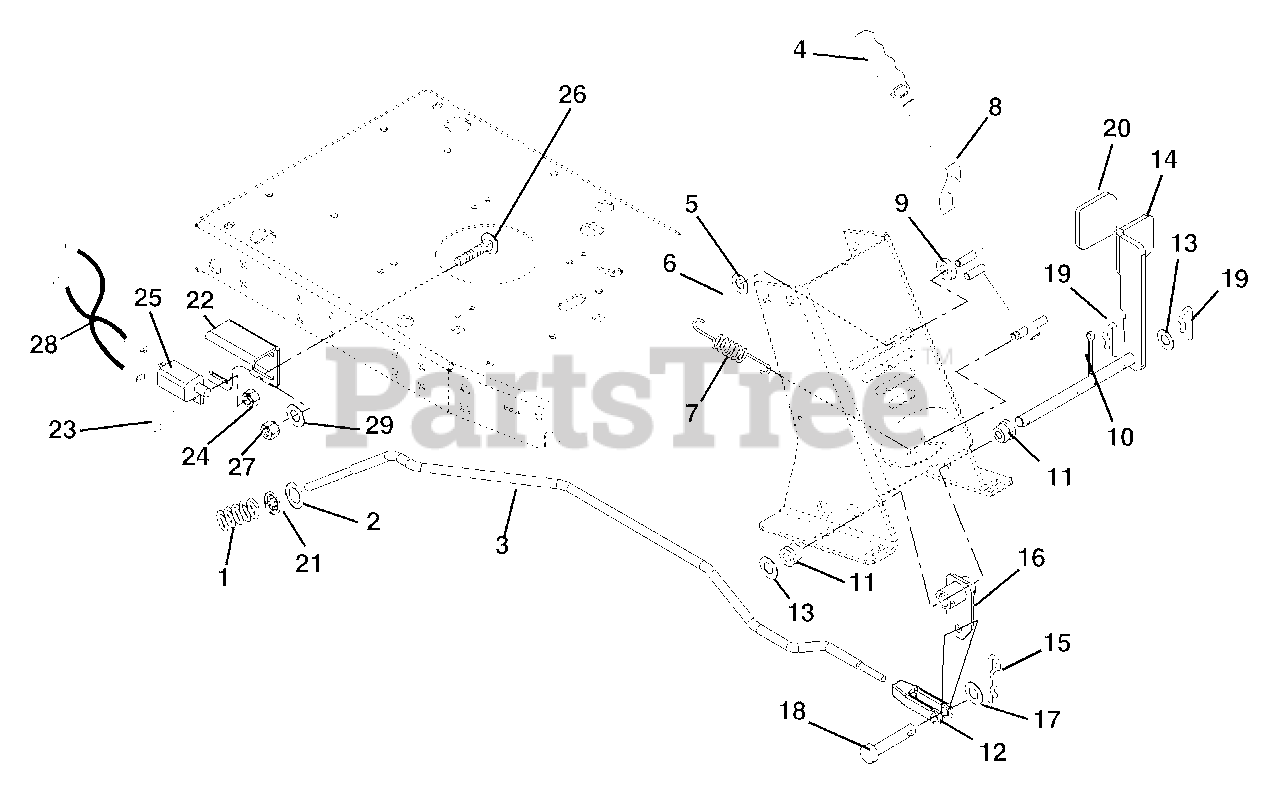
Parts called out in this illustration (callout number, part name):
1	SG-COMP .080X.52X2.90
2	WASHER, FLAT .33/2.125/.098
3	ROD, RER BRAKE
5	@WSHR-FL-STL.38X.875X.083 YWZC
6	NUT-LK-TOP-FLG .38-16 BLKZC
7	SG-TENS .048X.44X2.25 WLD 9
8	HANDLE, PARK BRAKE (WLDMNT)
9	BSHG-FLG .406X.88X.270X.140
10	@PIN-CTR .12X1.00 EXTPRSQCT YZ
11	BSHG-FLG .515X.750X.745X1.00NY
12	YOKE, .312-24 X 2.25
13	WSHR-FL-STL .505X1.00X.062YWZC
14	WLDMT-BRAKE PEDAL
15	PIN-HAIR, ENDRIES #25 YWZC
16	BRAKE ROD ARM & HUB
17	WSHR-FL-STL .328X.87X.179 YWZC
18	PIN-CLEV .312X.822 HDND PL
19	CLIP, SPRING
20	GRIP, PEDAL
21	NUT-PUSH .312
22	BRKT, SWITCH MOUNT
23	@SCR-MCH 10-24X.75 HWH YWZC
24	@NUT-LK-NYL 10-24 W/INSRT YWZC
25	SWITCH- SINGLE POLE N.O.
26	BLT-RDHDSQNK .38-16X1.00 G5BZ
27	@NUT-LK-NYL .38-16 YWZC
28	JUMPER, HARNESS
29	@WSHR-FL-STL.406X.812X.065 YWZ
